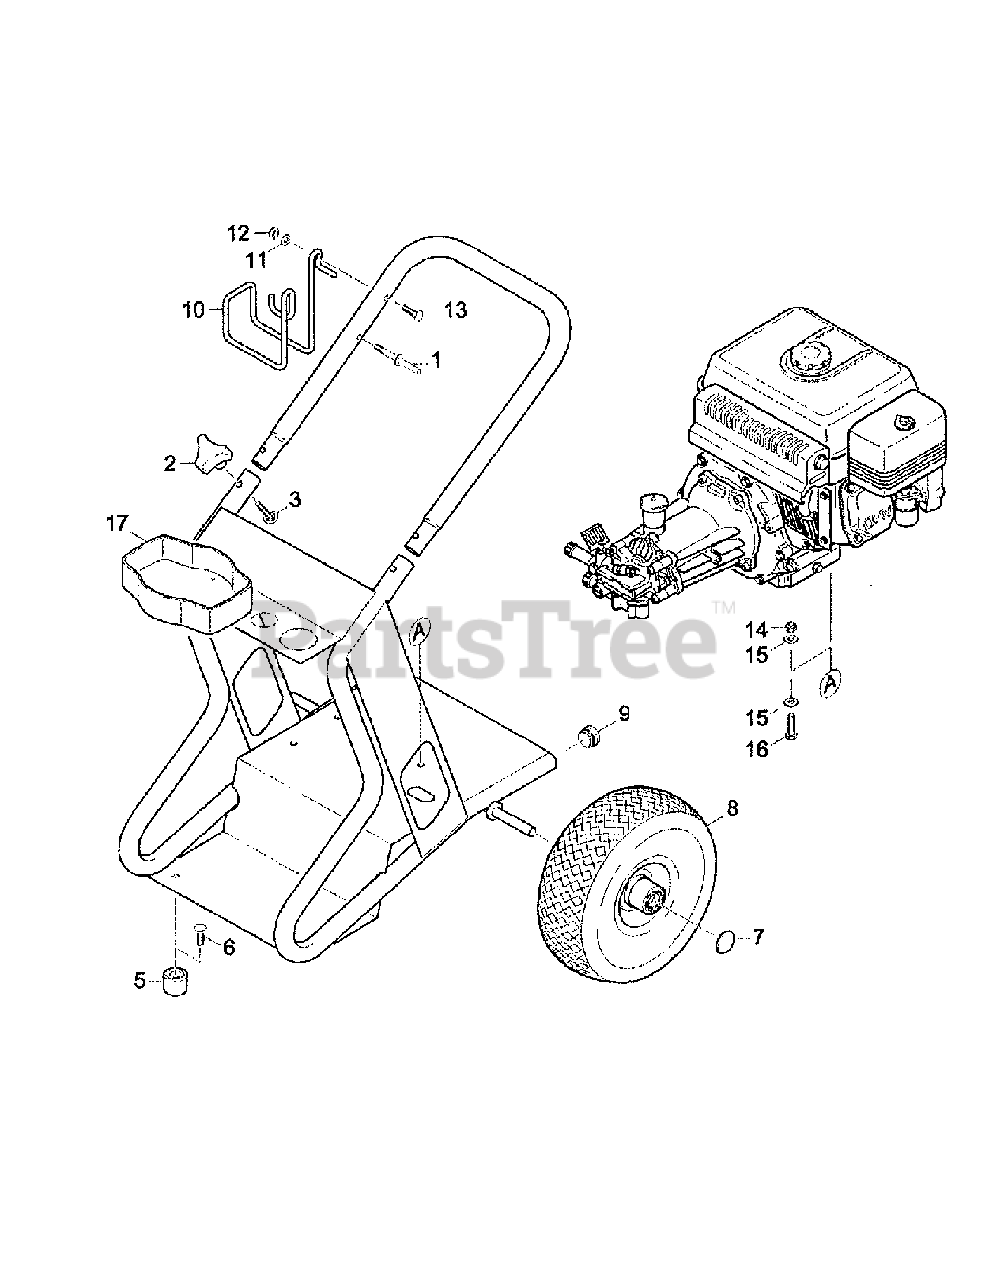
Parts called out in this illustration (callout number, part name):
1	Bolt 5/16"-18 x 1.75"
2	Control Knob
3	Screw 5/16"-18 x1.5"
5	Rubber Bumper
6	Bolt 5/16"-18 x 3/4"
7	Cap
8	Wheel 10" x 3.5"
9	Plug
10	Bracket
11	Washer
12	Nut
13	Screw 5/16"-18 x 1.75"
14	Nut 3/8"-16
15	Washer 3/8"
16	Screw 3/8"-16 x 2.0"
17	Tray, 1Gal. Chemical
